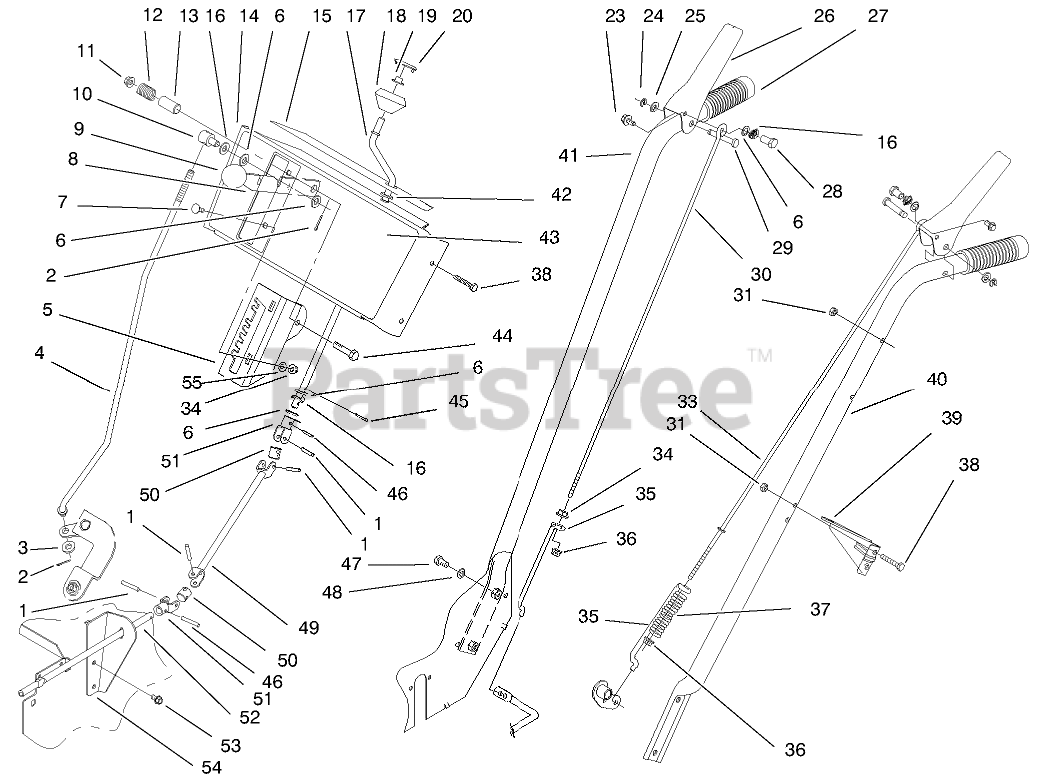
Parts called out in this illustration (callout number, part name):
1	PIN-SPRING
2	PIN-COTTER
3	WASHER-FLAT
4	ROD-SHIFT
5	MOUNT-SPEED SELECTOR
6	WASHER-FLAT
7	SCREW-CARR
8	SELECTOR-SPEED
10	TRUNNION
11	NUT-HF
13	SPACER
14	Panel-Control Asm (Only On: 38083)
14	Panel-Control Asm (Only On: 38084
15	Decal-Control Panel Back (Only On: 38084)
15	Decal-Control Panel Back (Only On: 38083)
16	WASHER-SPRING
17	ROD - CHUTE CRANK
18	KNOB-CONTROL, CHUTE
19	RETAINER-PUSH ON
20	COVER-KNOB
23	SCREW-HHF
24	RING-CLIP
25	WASHER-PLAIN
26	HANDLE-CONTROL
27	GRIP-HANDLE
28	POST-MOUNTING, LINKAGE
29	PIN-LEVER, CONTROL
30	ROD-UPPER ENGAGE AUGER
31	NUT-LOCK, NI
33	ROD-UPPER TRACTION
34	NUT-HF
35	ROD-LOWER TRACTION
36	NUT-HHF
37	SPRING
38	SCREW-HH
39	BKT-UPPER CRANK
40	LEFT HANDLE
41	HANDLE-RIGHT
42	Bushing
43	Decal-Control Panel
44	SCREW-HH
45	PIN-COTTER
46	PIN-SPRING
47	SCREW-HWHTF
48	WASHER-BELLEVILLE
49	WA - CLEVIS ROD
50	BLOCK - PIVOT
51	WA - CLEVIS MOUNT
52	ROD - CHUTE CONTROL
53	SCREW-HWH
54	BRKT-LOWER CRANK ROD (RED)
55	WASHER-FLAT
